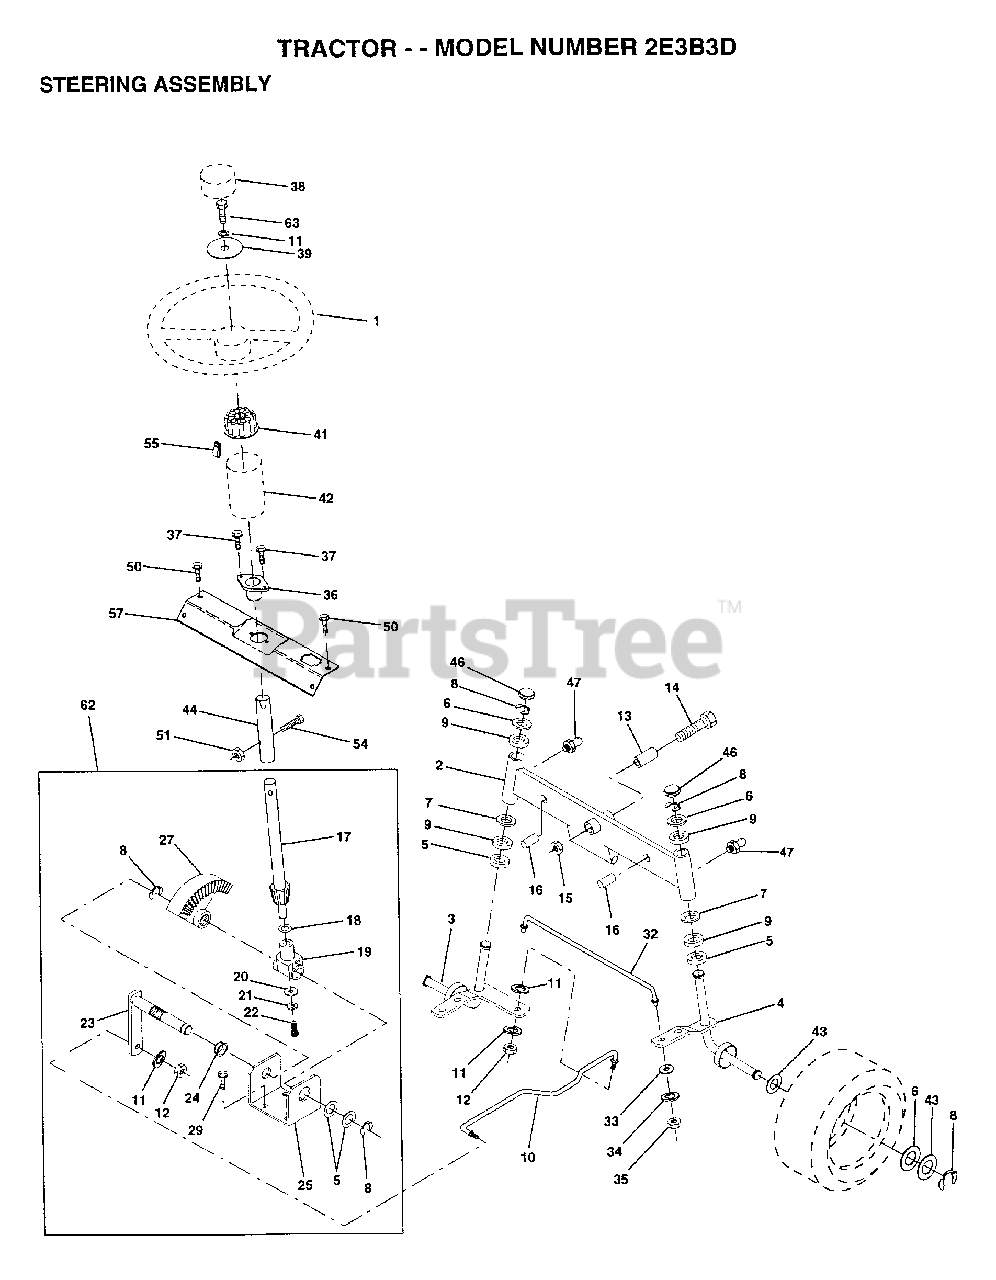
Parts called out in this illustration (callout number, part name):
2	AXLE ASM FRONT
3	SPINDLE LH
4	SPINDLE RH
5	WASHER .T
6	WASHER
7	WASHER
8	RING
9	COL. SRTG. BEAR.
11	LOCKWASHER
13	BEARING
14	BOLT HEX 5/8-11
15	"NUT-LOC,FLANGE LT"
16	AXLE PIN
17	SHAFT ASM
18	THRUST WASHER
19	SUPPORT.SHAFT
21	LOCKWASHER
22	SCREW.SCKTHD.CAP
24	NYLINER T
25	"BRKT,STEERING"
26	BUSHING.DRAGLINK
27	GEAR SECTOR
28	WASHER
29	SCREW
30	COTTER PIN
32	TIE ROD
37	"SCREW-TT,10-32 FL"
38	ST WHL INSERT CAP
39	WASHER T
40	GRIPCO NUT
41	ADAPTER-WHEEL LT
42	"TUBE, STR SHAFT"
43	WASHER
46	CAP
47	ZERK M
